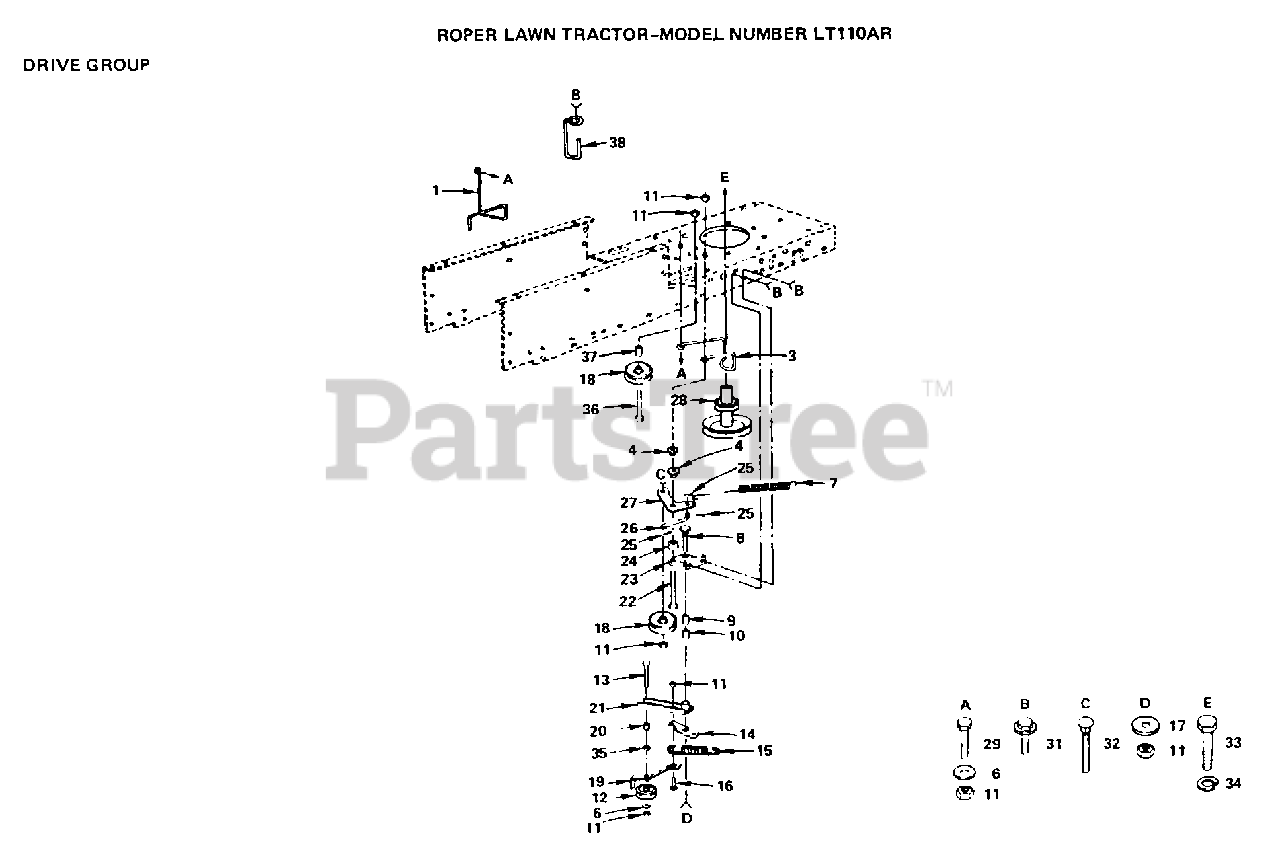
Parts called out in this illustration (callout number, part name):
1	GUIDE, BELT - ENGINE PULLEY
3	GUIDE BELT PLY LT
6	WASHER
7	SPRING CLUTCH LT
8	BOLT
12	IDLER.FLAT.GTV
13	BOLT
15	SPRING EXT LT
16	BOLT
17	WASHER
18	IDLER-FLAT LT
21	ARM IDLER ASSY LT
23	BRACKET SUPT LT
24	SPACER LT
25	COTTER PIN
26	LINK BELLCRANK
29	BOLT
31	SCREW
32	BOLT
34	LOCKWASHER
35	NUT.HEX.3/8-16UNC
36	BOLT
37	SPACER SPLIT LTV
